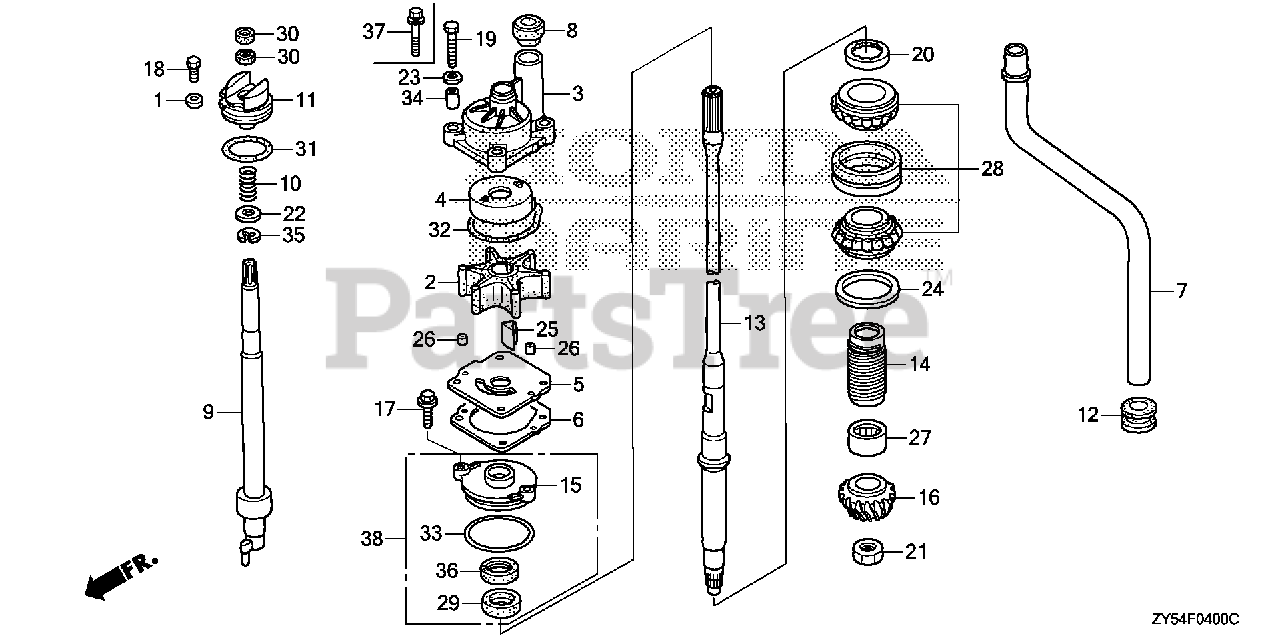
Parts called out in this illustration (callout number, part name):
1	WASHER, PIVOT
2	IMPELLER, PUMP
3	HOUSING, IMPELLER
4	LINER, PUMP
5	COVER, IMPELLER
6	GASKET B, IMPELLER
7	TUBE, WATER (XL)
8	RING, WATER TUBE SEAL
9	ROD, SHIFT (COUNTER ROTATION)
10	SPRING, SHIFT ROD
11	HOLDER, SHIFT ROD
12	GROMMET, EXTENSION CASE
13	SHAFT, VERTICAL (XL)
14	SLINGER, OIL
15	HOUSING, WATER SEAL
16	GEAR, PINION
17	BOLT, FLANGE (6X20) (ENGINE NO.)
18	BOLT, HEX. (6X12) Use up to Frame SN 1005248.
19	BOLT, HEX. (8X40)
20	NUT, LOCK (64MM)
21	NUT, HEX. (18MM)
22	WASHER, PLAIN (12MM)
23	WASHER (8MM)
24	SHIM A, GEAR (0.10)
24	SHIM B, GEAR (0.15)
24	SHIM C, GEAR (0.30)
24	SHIM D, GEAR (0.50)
25	KEY, WOODRUFF
26	PIN, DOWEL (6X10)
27	BEARING, NEEDLE (28.575X44.45X31.75)
28	BEARING, TAPER ROLLER (30X62X40)
29	SEAL, WATER (23X36X6) Use up to Frame SN 1300340.
29	SEAL, WATER (23X36X6)
30	SEAL, WATER (12X21X6)
31	O-RING (55.6X3.5)
32	O-RING, WATER PUMP
33	O-RING (58.5X3.5)
34	COLLAR, DISTANCE
35	E-RING (10MM)
36	SEAL, WATER (23X36X6) Use up to Frame SN 1300340.
36	SEAL, WATER (23X36X8)
37	BOLT-WASHER (8X40)
38	HOUSING KIT, WATER SEAL
